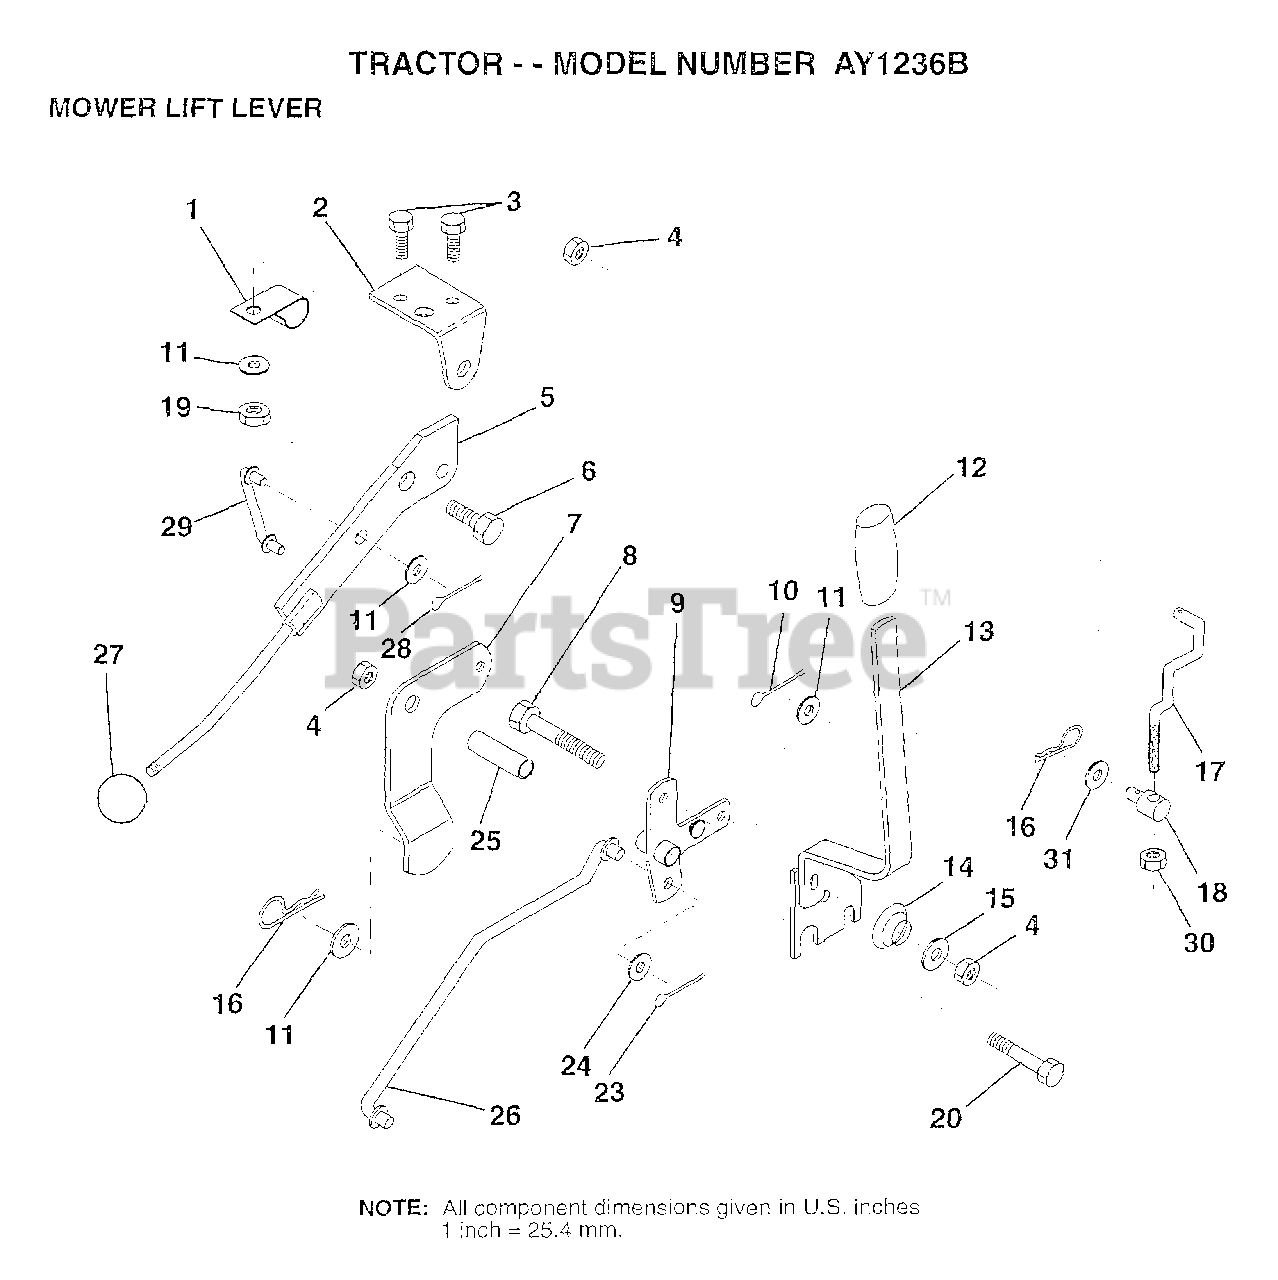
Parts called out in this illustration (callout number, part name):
1	"CLIP,INSULATOR"
2	BRKT CLUTCH
3	BOLT HXHD FIN
5	LEVER.ASM.CLUTCH
6	"BOLT, SHOULDER LT"
7	MWR CLUTCH ARM AS
8	BOLT
9	"BELLCRANK,LIFT"
10	COTTER PIN
11	WASHER
13	HANDLE.ASM.LIFT
14	SPRING COMPRESSIO
15	WASHER T
16	SPRING.RETAINER
17	"LINK,LIFT FRT"
18	TRUNION ADJ
20	BOLT
23	PIN COTTER 1/8
25	TUBE SPACER
26	ROD LIFT MOWER
27	KNOB T(3/8 HOLE)
29	CLUTCH LINK
30	NUT
31	WASHER
